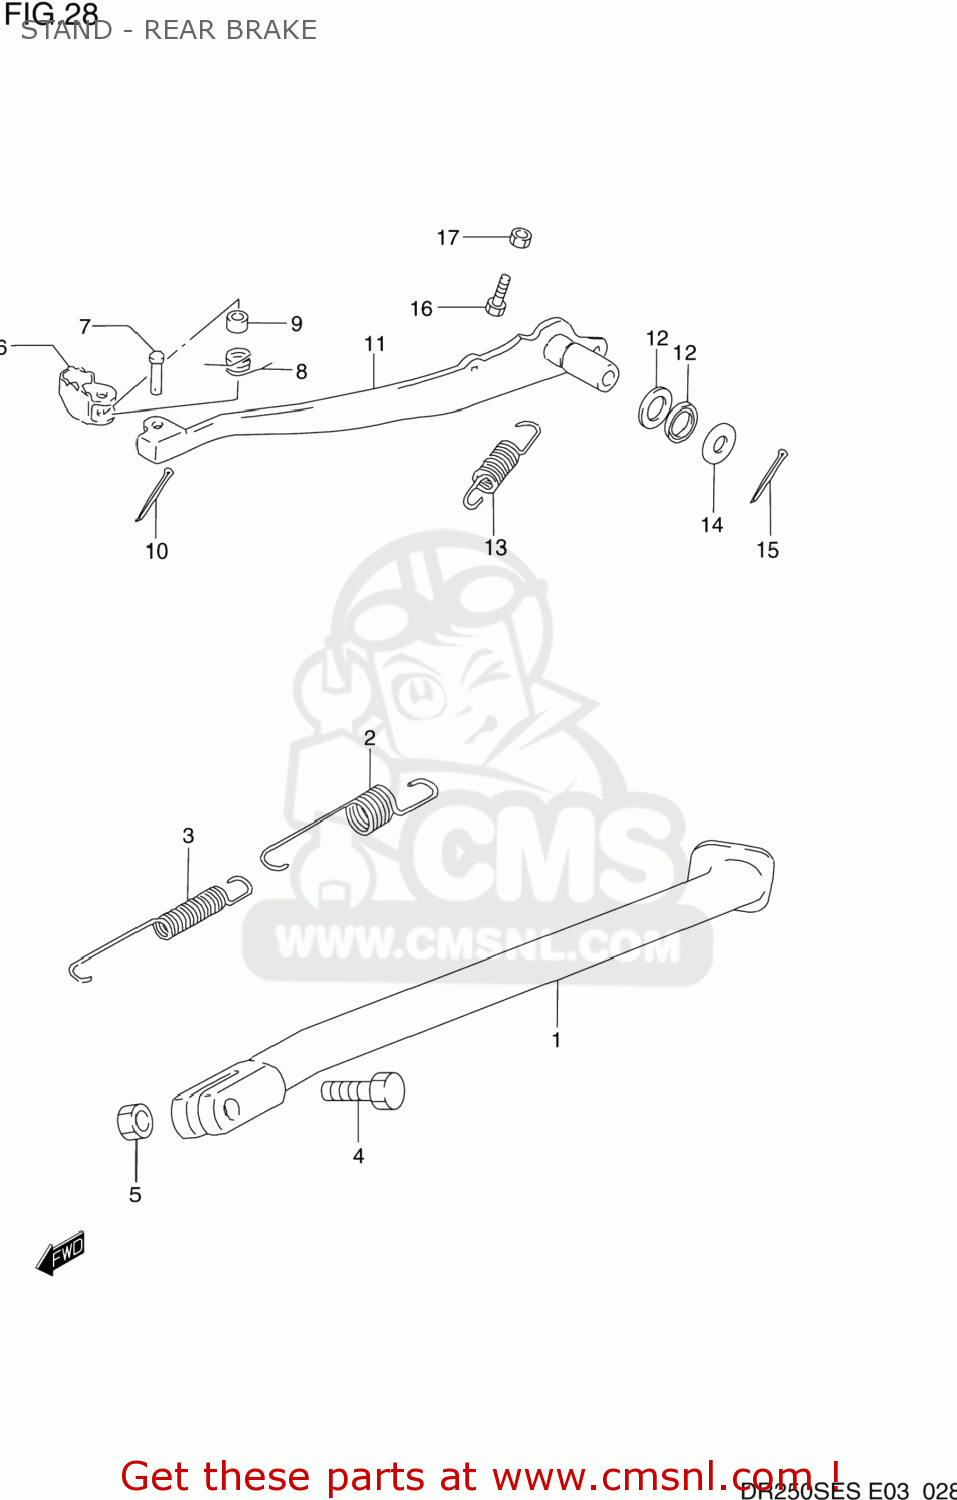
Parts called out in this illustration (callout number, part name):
1	STAND,SIDE
2	SPRING
3	SPRING
4	BOLT(10X30)
5	NUT
6	PEDAL,BRAKE
7	PIN
8	SPRING
9	SPACER(9.2X9X6.5)
10	PIN
11	ARM,BRAKE PEDAL
12	SEAL,OIL(15X21X3)
13	SPRING
14	WASHER(15.5X26X2.3)
15	COTTER PIN
16	BOLT(6X23)
17	NUT 6MM
